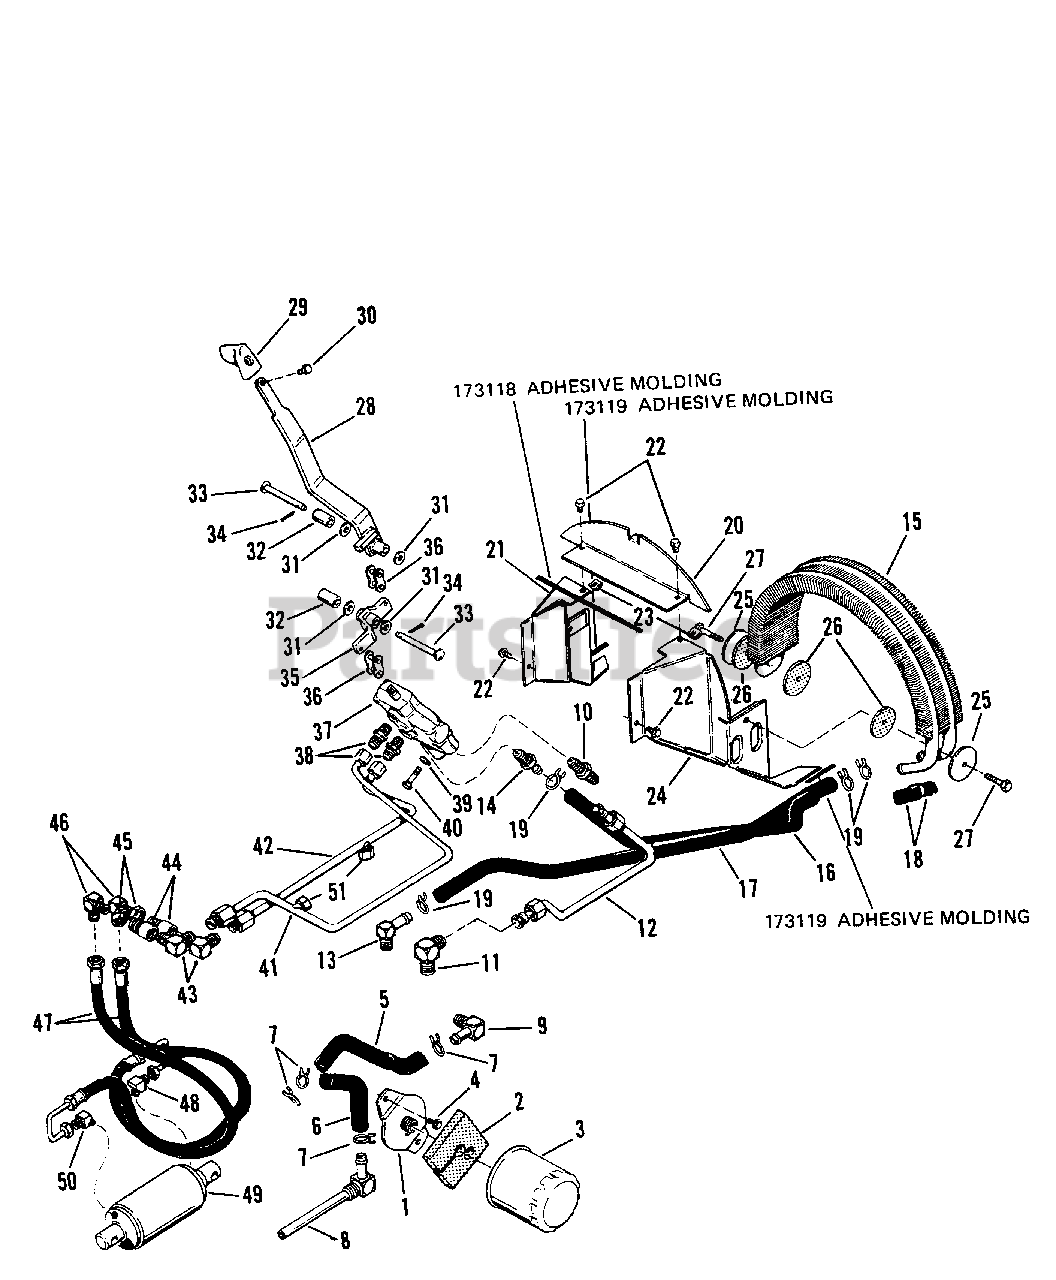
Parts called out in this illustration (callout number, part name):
1	Oil Filter Plate Assembly
3	Oil Filter
4	Hex Capscrew, 5/16"-18 x 1/2" lg.
5	Hydraulic Hose
6	Hydraulic Hose
7	Hose Clamp
8	Elbow Assembly
10	Male Connector
12	Tube Assembly
14	Hose Connector
15	Oil Cooler
16	Hydraulic Hose
17	Hydraulic Hose
18	Hydraulic Hose
19	Hose Clamp
20	Shroud, Upper Rear
21	Shroud Assembly, L.H.
22	Thread Forming Screw, 1/4"-20 x 3/8" lg.
23	Speed Nut
24	Shroud Assembly, R.H.
27	Thread Forming Screw, 1/4"-20 x 1-1/2" lg.
28	Valve Lever Assembly
30	Thread Forming Screw, 1/4"-20 x 3/4" lg.
31	Plain Washer, 5/16"
33	Pivot Pin
34	Cotter Pin, 3/32" x 5/8" lg.
35	Valve Bellcrank Assembly
36	Connecting Link
37	Hydraulic Valve
38	Male Connector
39	Lock Washer, 1/4"
40	Hex Capscrew, 1/4"-20 x 1-3/4" lg.
41	Tube Assembly
42	Tube Assembly
